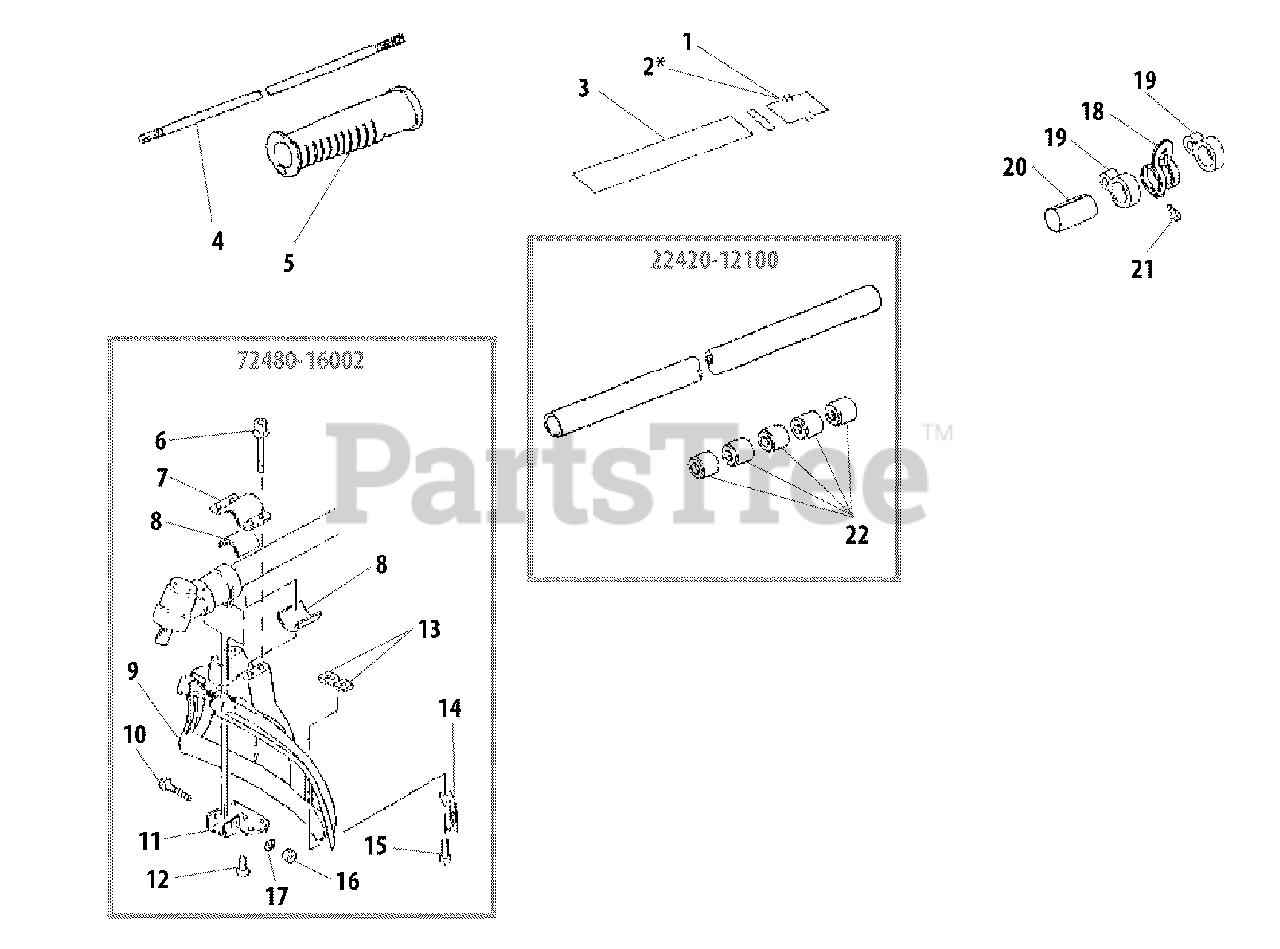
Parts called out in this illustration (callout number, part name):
1	LABEL - MODEL
2	LABEL - TRADE
3	LABEL - CAUTION
4	PIPE, MAIN
5	GRIP - REAR
6	SCREW - 5X45
7	CLAMP - UPPER
8	SPACER
9	SHIELD, DEBRIS
10	SCREW - 5X35
11	CLAMP - LOWER
12	SCREW
13	NUT - 5
14	KNIFE, TRIMMER LINE
15	SCREW - 5X16
17	WASHER - 5
18	HANGER
19	GUIDE
20	SPACER
21	SCREW - 5X12
22	BUSHING
A	DEBRIS SHIELD KIT
A	MAIN PIPE ASSY
